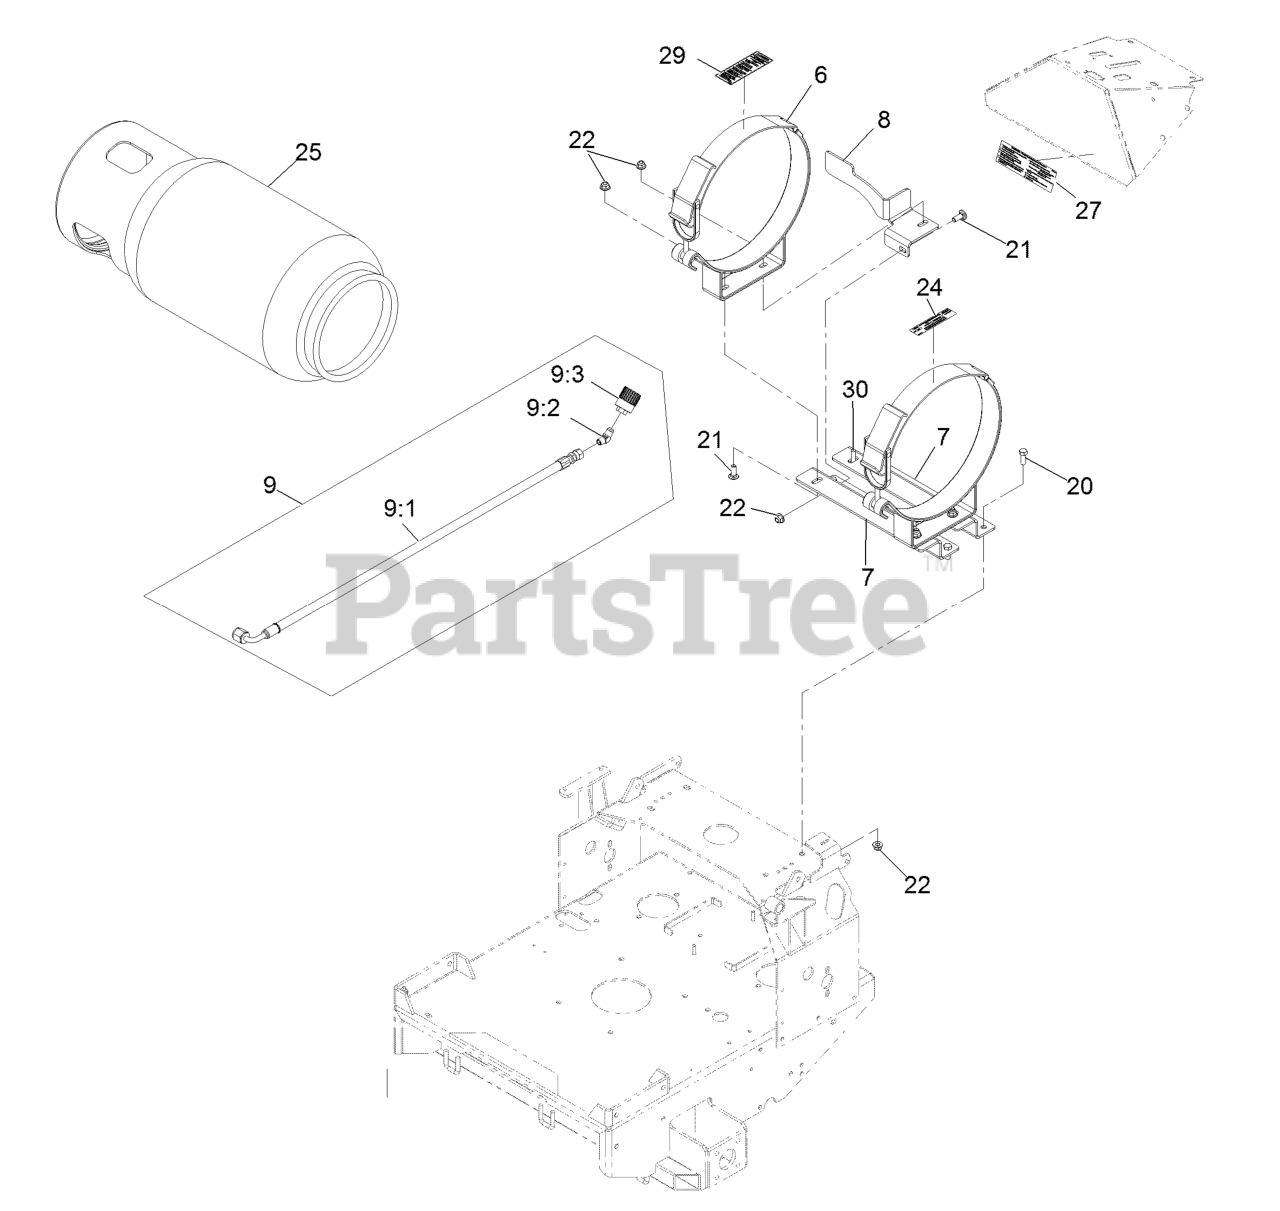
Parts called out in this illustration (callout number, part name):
6	BRACKETS, LPG TANK - HORI
7	RISER, LPG TANK
8	BRACKET, LPG TANK INDEX
9	Asm, Lpg Fuel Hose
9:1	LPG FUEL HOSE ASM
9:2	ELBOW-45 DEG
9:3	CONNECTOR-LPG TANK, LH TH
20	SCREW-HH
21	SCREW-CARR
22	NUT-HF, NI
24	DECAL,LPG TANK SPEC HORIZ
25	TANK,LPG 33LB
27	DECAL-TANK REPLACEMENT
29	DECAL-LPG WARNING
30	BOLT-CARR
